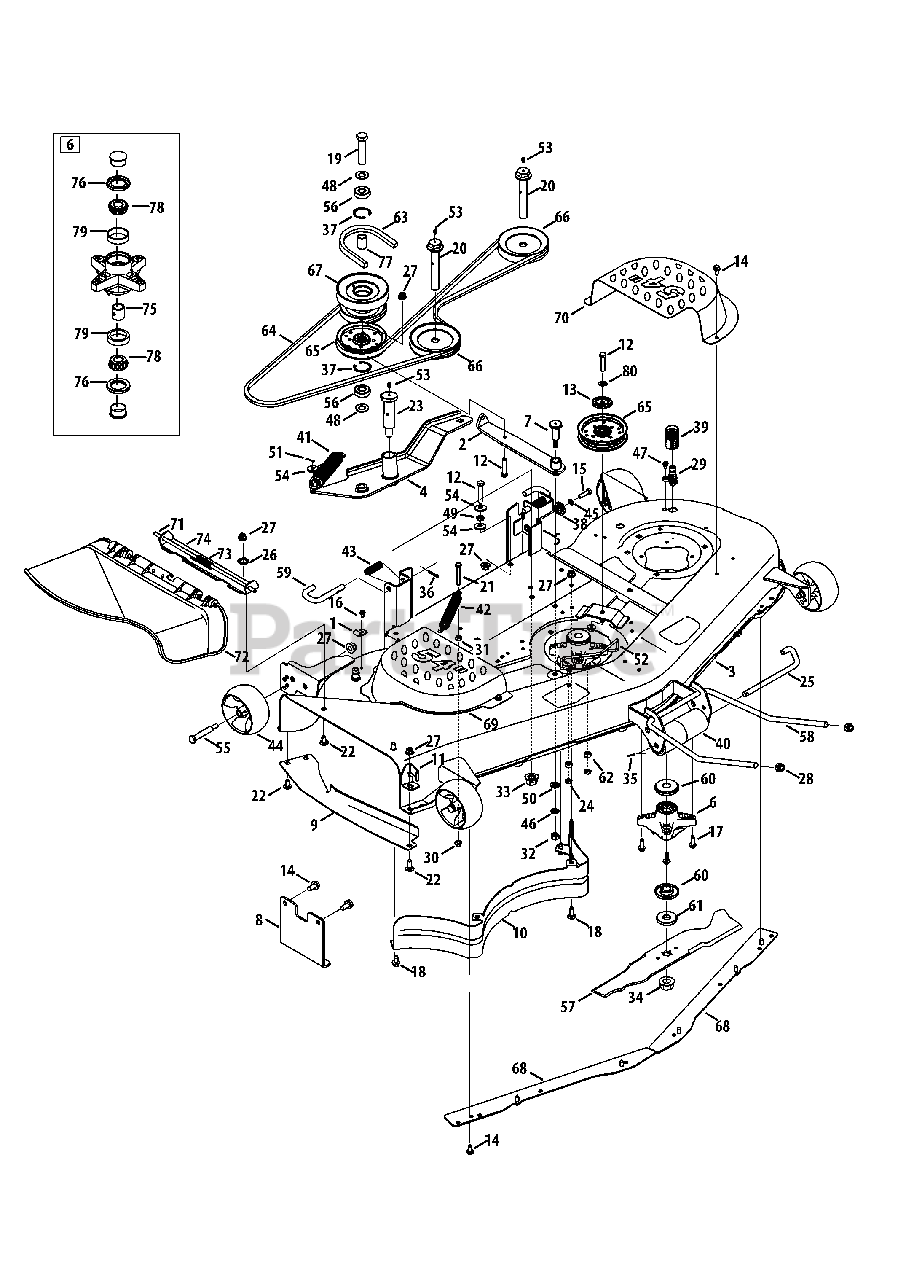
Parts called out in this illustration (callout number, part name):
1	Hook Retainer Bracket
2	Idler Assembly
5	Hanger Adjustment Bracket
6	Spindle Assembly
7	Shoulder Bolt
8	Up-Stop Bracket
11	Chute Deflector Stop
12	Hex Screw, 3/8-16 x :1.75
13	Pulley Cap
14	Hex Washer Screw, 5/16-18 x .750
15	Hex Screw, 5/16-18 x 1.25
16	Hex Washer Screw, 1/4-20 x .500
17	Hex Washer Screw, 5/16-18 x 1.000
18	Hex Washer Screw, 3/8-16 x .750
19	Hex Screw, 5/8-18 x 3.00
20	Spindle Bolt, 3/4-16 x 5.215
21	Hex Screw, 5/16-18 x 2.25
22	Carriage Bolt, 3/8-16 x 1.00
23	Shoulder Screw, 1.0 x 3.00
24	Hex Lock Nut, 1/4-20
25	Roller Pin, 1/2 x 7.31
26	Push Nut, 3/8
27	Flange Lock Nut, 3/8-16
28	Flex Lock Nut, 1/2-13
29	Deck Wash Nozzle
30	Flange Lock Nut, 5/16-18
31	Hex Nut, 5/16-18
32	Hex Nut, 7/16-14
33	Flange Lock Nut, 5/8-18
34	Flange Lock Nut, 3/4-16
35	Cotter Pin, 3/32 x 1.25
36	Cotter Pin, 5/32 x 1.25
37	Retainer Ring
38	Deck Adjustment Gear
39	Water Nozzle Adapter
40	Front Roller
41	Extension Spring, 1.25 x 6.9
42	Extension Spring, 1.0 x 6.42
43	Compression Spring, .66 x 1.8
44	Deck Wheel, 5.0
45	Lock Washer, 5/16
46	Lock Washer, 7/16
47	Shoulder Screw, 1/4-20 x 0.50
48	Flat Washer, .65 x 1.25 x .075
49	Jam Nut, 3/8 x 16
50	Flat Washer, .469 x .875 x .105
51	Cotter Pin, 3/32 x .750
52	Belt Drive Guard
53	Drive Lube Fitting, 3/16
54	Falt Washer, .385 x 1.00 x .135
55	Shoulder Screw, 1/2 x 2.50
56	Ball Bearing, .625 x 40 x 12
57	Blade
58	Front Lift Rod
59	Mower Support Pin
60	Deck Spindle Spacer
61	Blade Spacer, 2 x .75 x .31
62	Spacer, .256 x .500 x .240
64	Deck Belt
65	Idler Pulley
66	Spindle Pulley
67	Double Pulley
69	RH Belt Cover
70	LH Belt Cover
71	Hinge Pin, .3175 x 14.06
72	Chute Deflector
73	Torsion Spring, .44 x 2.0
74	Chute Bracket
75	Bearing Spacer, .78 x 1.0 x 1.0425
77	Spacer, .88 x .635 x 1.25
78	Cone Bearing, .750
79	Bearing Cup, .750
80	Flat Washer, .406 x .812 x .051
